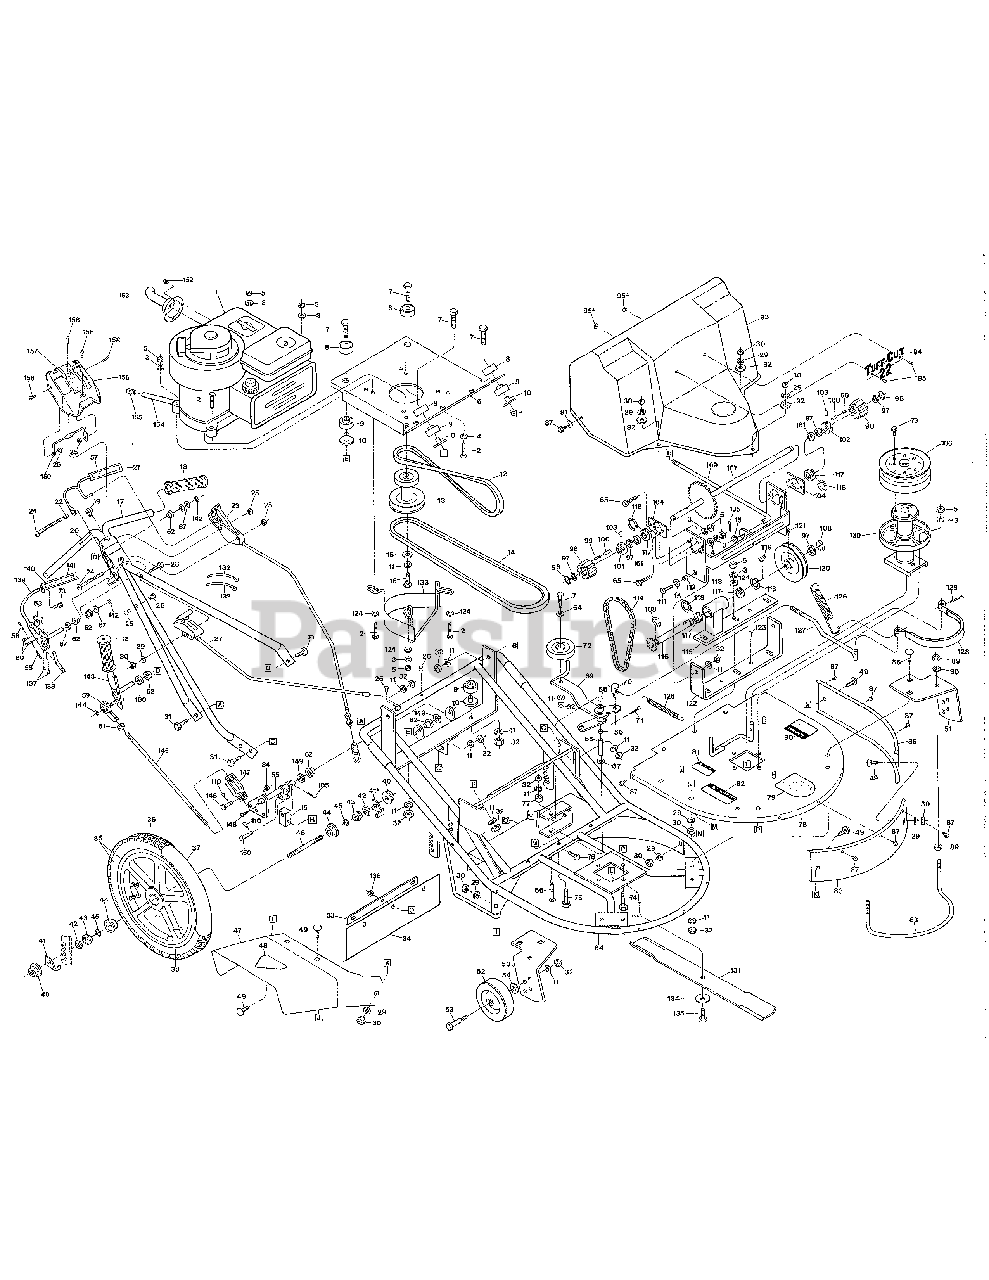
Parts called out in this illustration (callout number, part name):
2	SCR-HH 5/16-18X1.75
3	WASHER-LK .312 ZP
4	WASHER-.88X312X.08 ZP
5	NUT-HEX 5/16-18 ZP
6	BASE-ENGINE PNT
7	SCR-HH 3/8-16X2.0 G5 ZP
8	REBOUND MOUNT-24"
9	LOAD CARRYING MOUNT-24"
10	TUB-SPACER 24"
11	WASHER-LK .375 @@ DEPLð
12	TRACTION-V BELT
13	PULLEY-ENGINE
14	BLADE-V BELT
15	WASHER-1.0X.438X.104 ZP
16	SCR-HH 3/8-24X1.5 G5
17	ASSM-HANDLEBAR S-P (INCL. 18 - 2 GRIPS AND 20)
18	GRIP-HANDLEBAR
19	PLUG-METAL CAP
20	DECAL-STARTING INST
21	ASSM-BLADE CONTROL HANDLE (INCL 57)
23	CABLE-BLADE DRIVE (LATCH & CABLE)
24	SCR-PHP M10-24X4.0 ZP
25	NUT-HEX LOCK #10-24 PL
26	PLUG-HOLE (ENGINES ONLY)
27	SPEED CONTROL-ENGINE (CABLE AND CONTROL)
28	SCR 1/4-20X1.5 PL CSHH
29	WASHER-LK .25 ZP
30	NUT-HEX 1/4-20 ZP
31	SCR-HH 3/8-16X.75 G5 ZP
32	NUT-HEX 3/8-16 ZP
33	BRKT-PROT TRAILER PNT
34	TRAILER-MOWER
35	ASSM-TIRE & WHEEL {36,37,38,39,40,42,43,44, 45,46}
36	TIRE-16 X 2.125
37	TUBE-16"
38	ASSM-16" RIM {40,42,43,44,45,46}
39	CAP-VALVE
40	NUT-HF/LK 3/8-24 WHIZ
41	TAB-WHEEL LOCK RH
41A	TAB-WHEEL LOCK LH
42	NUT-LOCK 3/8-24 PL
43	NUT-ACORN 3/8-24 ZP
45	BEARING-WHEEL
46	AXLE-WHEEL
47	CHUTE-DISCHARGE W/DECAL (INCL 48)
48	DECAL-BLADE WARNING
49	SCR-CARR 1/4-20X.375
50	HANGER-RT WHL PNT
51	HANGER-LT WHL PNT
52	ASSM-TIRE&WHL FRONT
53	SCR-SHLDR 3/8-16X1.406
54	SPROCKET-21T
55	WELD-BELLCRANK PLATED
56	BEARING-SLEEVE
57	STICKER-BLADE BAIL
58	PIN-COTTER .09X.75 ZP
59	JOINT-BALL
60	PIN-CLEVIS .248X1.0 ZP
61	NUT-HEX/JAM 3/8-24 ZP
62	BUSHING-.62X.5X.43 FLNG
63	LATCH-TOGGLE
64	FRAME-22" WELD PNT
65	SCR-HHCS 5/16-18X7/8GR5
66	SCR-HH 3/8-16X4.5 G5
67	SHIM-WASHER
68	TUBE-PIVOT
69	ARM-IDLER W/BUSHINGS (INCL. 2 BEARINGS NO 56)
70	TRUNNION
71	PIN-COTTER .094X1.0
72	PULLEY-IDLER
73	SCR-SELFTAP 5/16-18X5/8
74	SCR-HHC 5/16-18X.75 GR 5 ZP
75	SCR-HH 5/16-18X2.25 G5ZP
76	SCR-HHC 5/16-18X.75 GR 5 ZP
77	SPACER-.625X.387X1.0 ZP
78	ASSM-DECK TOP 22" (INCL. 79-82)
79	DECAL-LOGO 22"
80	DECAL-WARNING PROCEDURES
81	DECAL-CAUTION BELT COVER
82	DECAL-DANGER GUARD
83	WRAP-FRONT 22" PNT
84	NUT W/LKWASHER 10-24 ZP
85	WRAP-LH PNT
86	SCR-CARR 3/8-16X1.00
87	SCR-HW M10-16X.75 SELT DR
88	BUMPER-22" PNT
89	NUT-HEX JAM 1/2-13
90	WASHER-LK .5
91	WASHER-#10 TYPE B PLN ZP
92	WASHER-FLAT 1/4 SAE
93	COVER-BELT 22" TROY-BILT
93	KIT-SVC 22" BELT COVER TUFF-CUT
94	PLATE-NAME TROY-BILT
94	PLATE-NAME 22" TUFF-CUT
95	RIVET-POPOP
95A	WASHER-RIVETING
96	RING-HEAVY EXT .575 ID
97	WASHER-1.0X.632X.03 ZP
98	ROLLER-DRIVE
99	SPRING-DOWEL RETURN
100	PIN-DOWEL 1/4"
101	RATCHET-RH MACH
102	RATCHET-LH MACH
103	PIN-ROLL 3/16 X 1.5
104	PLATE-BEARING PNT
105	PIN-COTTER 1/8-1.00
106	KIT-PULLEY W/SCRS TC II (INCL. 3 SCREWS NO. 73)
107	SHAFT-DRIVE POLISHED 22"
108	RING-RETAINING "E"
109	ROD-TRAC DR LINK PNT
110	CLIP-HITCH PIN #13 PL
111	SCR-HH 3/8-16X1.0 G5 ZP
112	SPACER-.390X.630X.281
113	BRKT-TRACTION DR PNT
114	CHAIN #35-46 PITCHES
115	BRKT-JACKSFT MTG PNT
116	JACKSFT-WELD HEAT TREAT
117	BEARING
118	RING-RETAINING EXTERNAL
119	KEY-HI PRO 1/8X1/2
120	PULLEY-WHEEL DRIVE
121	SCR-SET 1/4-20X1/4
122	BRKT-U CHANNEL PNT
123	PIN-ROLL 1/4X1/2
124	WASHER
125	SPRING-WHEEL OR RETURN
126	SPRING-SPINDLE BRAKE
127	ROD-BRAKE ENGAGEMENT
128	BRAKE BAND & LINING
129	PIN-COTTER 1/8X3/4
130	KIT-SPINDLE TUFFCUT I&II (INCL. PULLEY NO 106 & SPINDLE MOUNTING HARDWARE)
131	BLADE-22" TUFFCUT NLA
132	TIE-RED
133	GUIDE-BELT PNT
134	WASHER-BELLEVILLE 3/8
135	SCR-HH 3/8-24 X 1.5" G8
136	NUT-H/LK 5/16-18
139	BAIL W/SPRING (INCL. 138 & 138)
140	ASSM-WHEEL DR HANDLE (INCL. 141)
141	STICKER-TRACTION BAIL
142	RING-RETAINING EXTERNAL
143	ASSM-WHL DR LEVER W/GRIP (INCL. 18)
144	RING-RETAINING EXTERNAL
145	LINK-HANDLE
146	PIN-CLEVIS
147	CLEVIS (PLATED)
148	SCR-PHP 10-24X.625 ZP
149	WASHER-#.88X.51X.063 ZP
150	PIN-CLEVIS
151	ADJ-BLOCK PLATED
152	SCR-SELF TAP
153	PIPE-EXHAUST EXT PNT
154	PIPE-OIL DRAIN
155	PLUG-PIPE 1/4 NPT
156	SHROUD-CNTRL W/DECAL (INCL. 157)
157	STICKER-OPER INST
158	SCR-PH PLPS 3/16-24X1/2
159	BRACE-PANEL
160	NUT-HFLK 3/8-16 ZP
161	SPACER-.640X7/8X1/8LEDLOY
